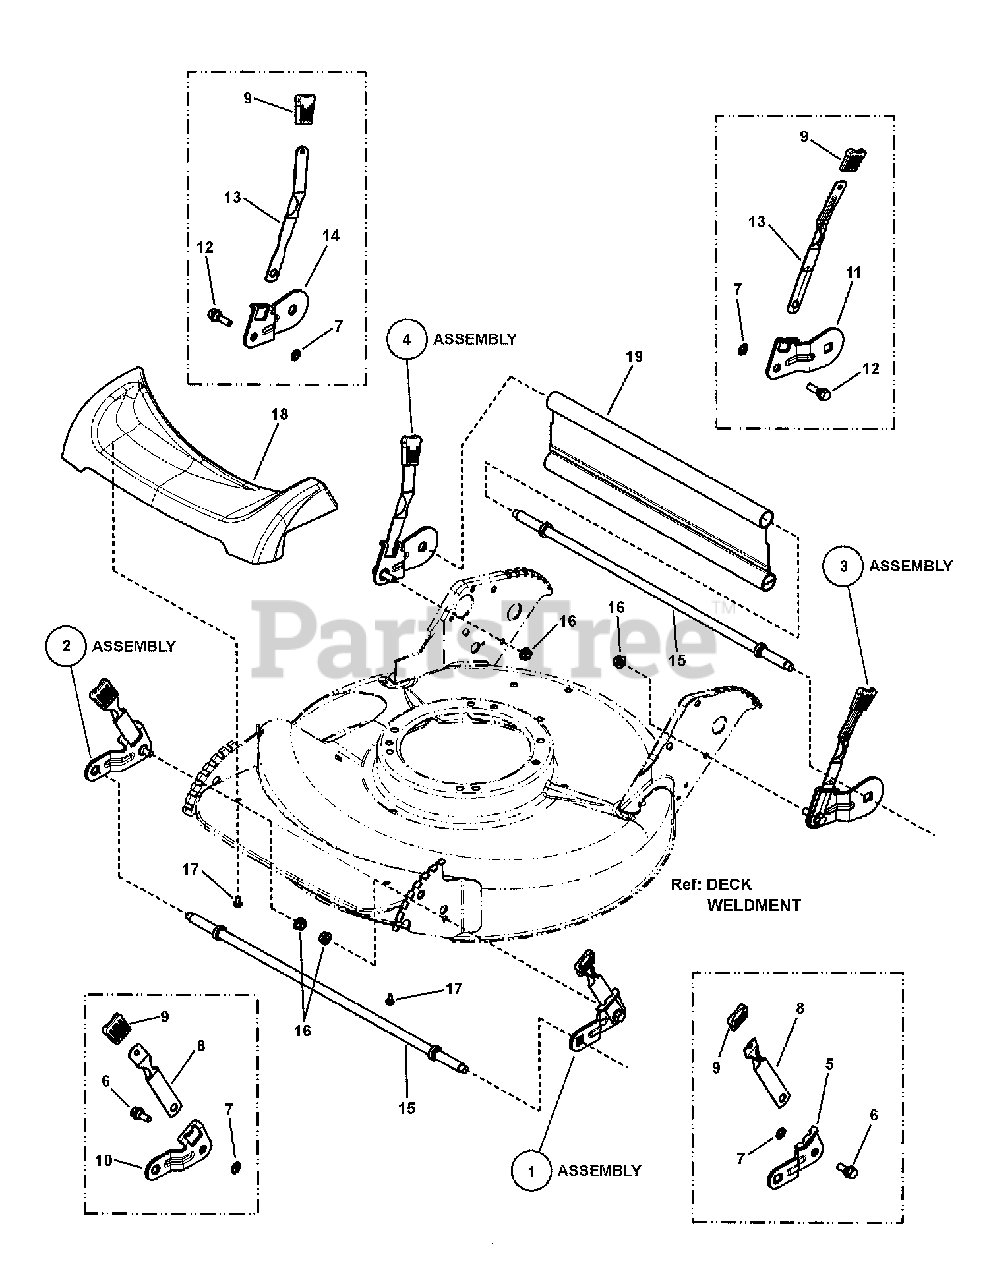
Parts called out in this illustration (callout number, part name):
1	ASSEMBLY, Left Wheel Arm (.512" Square Hole)
2	ASSEMBLY, Right Wheel Arm
3	ASSEMBLY, Wheel Arm, Left Rear Long (Push)
4	ASSEMBLY, Wheel Arm, Right Rear (Push)
5	WHEEL ARM, L.H. Front (.512" Square Hole)
6	BOLT, 5/16-18 x 3/4" Hex Washer Face Shoulder
7	RETAINER, 5/16" Bolt
8	LATCH, Height
9	GRIP, Height Latch - Black (1.3" Wide)
9	GRIP, Height Latch - Black (1.7" Wide)(use on rear)
10	WHEEL ARM, R.H. Front (Round Hole)
11	ARM, Wheel, Left Rear
12	BOLT, 5/16-18 x 1" Hex Washer Face Shoulder
13	LATCH, Height Adjusting (long)
14	ARM, Wheel, Right Rear
15	AXLE, Front, Easy Line (3/8-16 Threads)
16	NUT, 5/16-18 Hex Flange Lock, GR 5
17	SCREW, Round Washer Head Torx, Hi-Lo
18	COVER, Front 21" walk
19	GUARD, Rear (21 Push)
